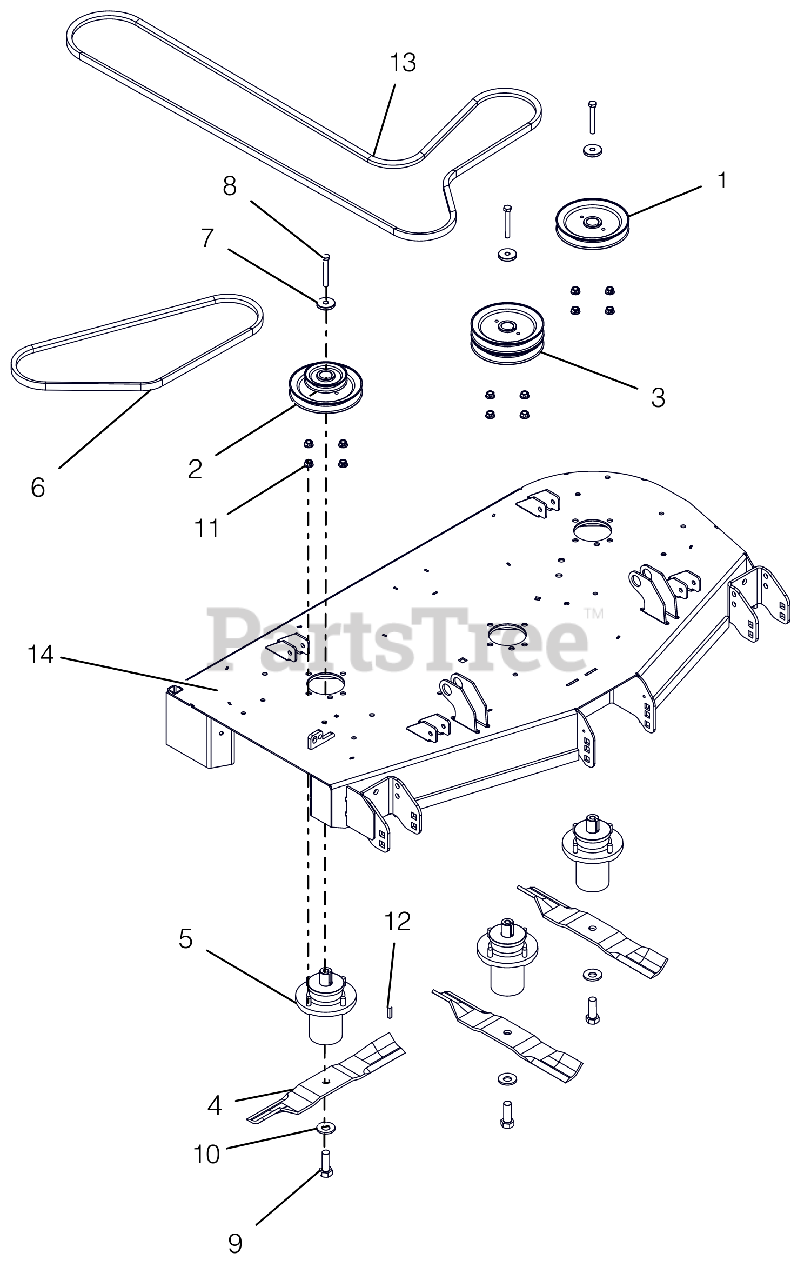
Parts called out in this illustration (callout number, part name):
1	PULLEY, SINGLE-1"ID X 6" OD
2	PULLEY, DOUBLE-1"IDX3.50"&6.0
3	PULLEY, DOUBLE
4	BLADE, 16.19" MOWER (HI-LIFT)
5	ASM, MAINT FREE SPINDLE ALUM
6	V-BELT, B-COGGED
7	RETAINER, SHEAVE
8	BLT-HEX .38-16X2.75 GR8 YWZC
9	BLT-HEX .62-18X1.75 GR8 YWZC
10	WSHR-BLVL .669X1.535X.138
11	NUT-LK-CTR-FLG .38-16 YWZC
12	KEY, SQ .25X.25X1.00 RC 40-50
13	V-BELT, HB SECTION
14	KIT,DECK-48" W/DECALS - ARIENS
